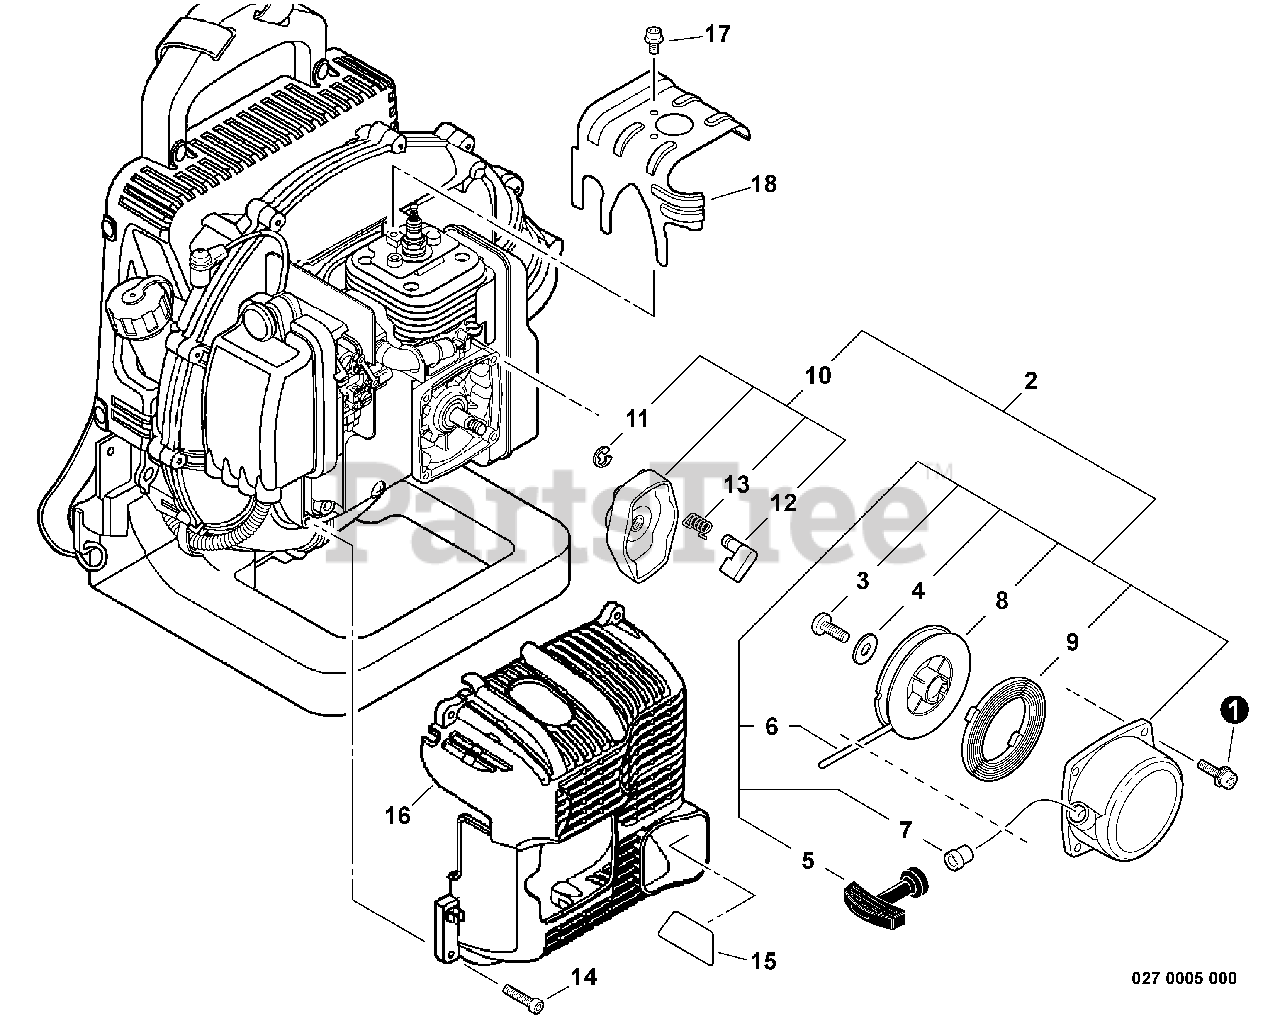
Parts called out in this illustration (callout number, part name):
1	BOLT 5×18
2	STARTER ASSY
5	GRIP, STARTER
6	ROPE, STARTER 3.8×1400
7	GUIDE, ROPE
8	REEL, ROPE
9	SPRING, RECOIL
10	PAWL ASSY, STARTER
11	E-RING 4
12	PAWL, STARTER
13	SPRING, RETURN
14	SCREW TAPPING 5×20
15	DEFLECTOR, HEAT
16	COVER, ENGINE
17	BOLT 5×8
18	COVER, CYLINDER
